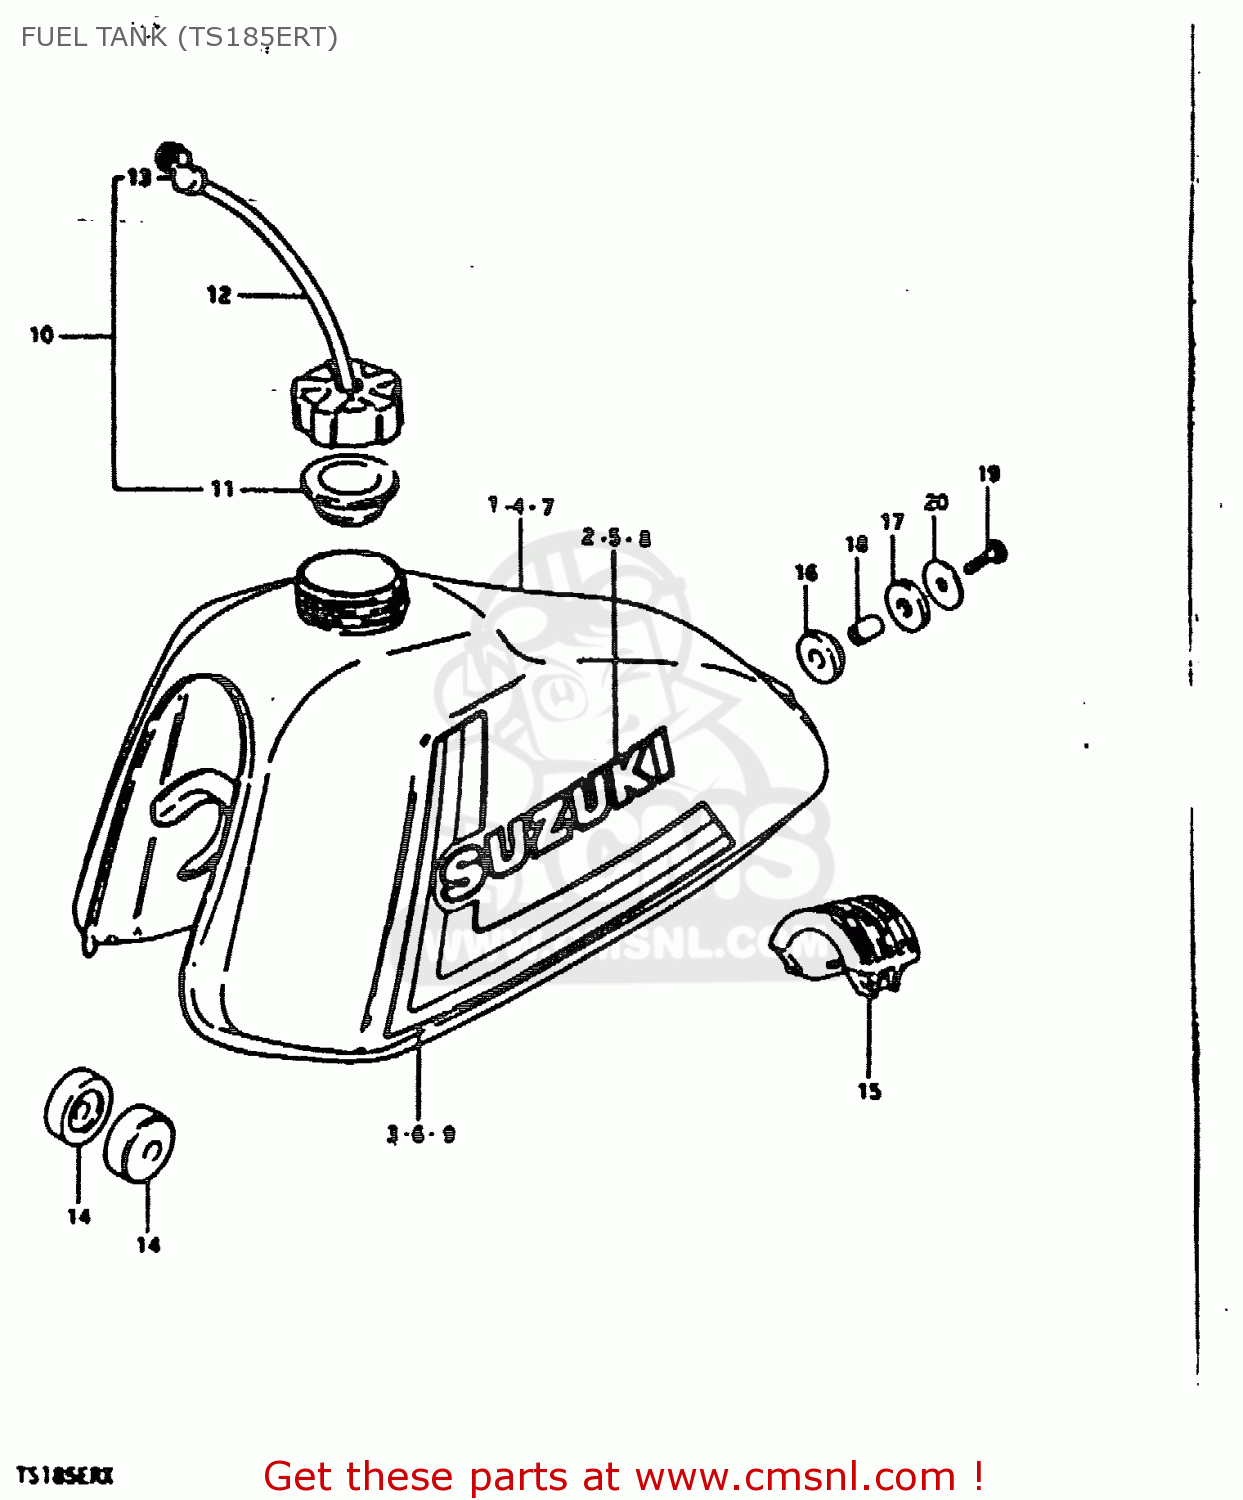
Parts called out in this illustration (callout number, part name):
1	TANK, FUEL (RED)
2	EMBLEM
3	TAPE SET
4	TANK, FUEL (BLUE)
5	EMBLEM
6	TAPE SET
7	TANK, FUEL
8	EMBLEM
9	TAPE SET
10	CAP SET,FUEL TANK
11	GASKET,FUEL TANK CAP (NAS)
12	HOSE
13	CLAMP,FUEL TANK BREATHER HOSE
14	CUSHION
15	CUSHION,FUEL TANK
16	CUSHION
17	CUSHION
18	SPACER(8.5X12X19)
19	BOLT (8X30)
20	WASHER (8.5X29X1.6)
